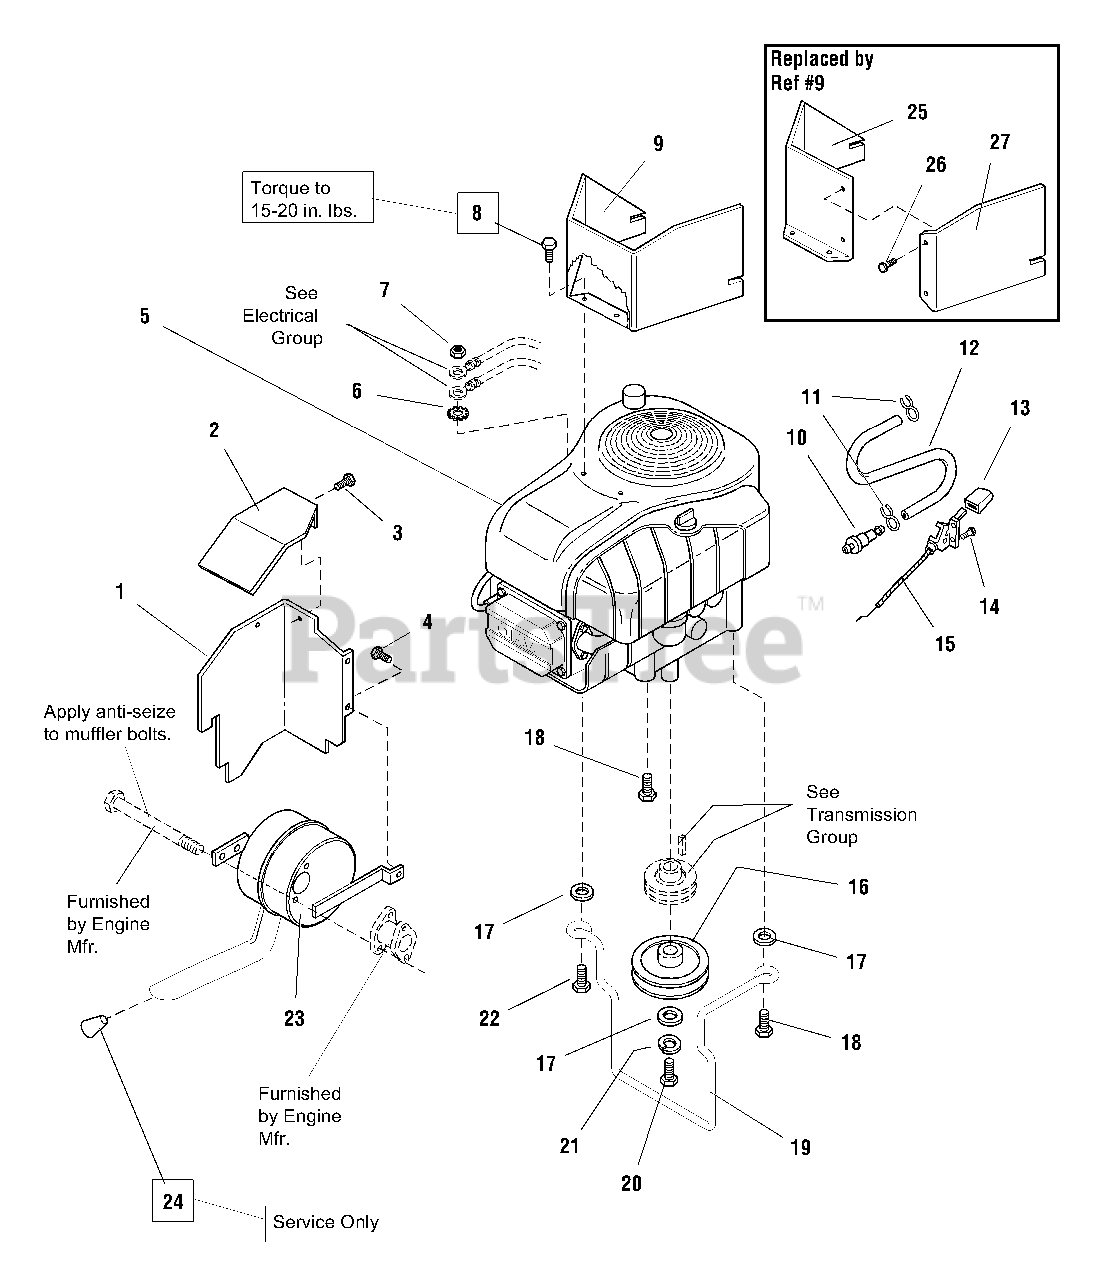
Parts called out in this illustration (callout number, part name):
1	SHIELD, Muffler Side
2	SHIELD, Muffler Top
3	CAPSCREW, Hex Washer Hd, Plastite, #10 - 14 x 5/8
4	CAPSCREW, Taptite Hex Washer Hd, 5/16-18 x 1/2
5	ENGINE, 14.5HP Briggs & Stratton INTEK
5	ENGINE, 15.5HP Briggs & Stratton INTEK
5	ENGINE, 17HP Briggs & Stratton INTEK
6	LOCKWASHER, External Tooth, 3/8
7	NUT, Hex, 3/8-16 NC-2B
8	CAPSCREW, Whiz Lock Hex Hd, 5/16-18 x 1/2
9	BAFFLE, Heat
10	FUEL FILTER
12	HOSE, Fuel, 1/4 ID x 1/2 OD x 12
13	KNOB, Throttle (Red)
14	CAPSCREW, Plastite Hex Washer Hd, 1/4-10 x 5/8
15	CONTROL, Throttle
16	PULLEY (with Hub)
17	WASHER, 7/16
18	CAPSCREW, Hex Washer Hd, Taptite, 3/8-16 x 1-1/2
19	GUIDE, Belt
20	CAPSCREW, Hex Hd, 7/16-20 x 2-1/2
21	LOCKWASHER, 7/16
22	CAPSCREW, Hex Washer Hd, Taptite, 3/8-16 x 2
23	MUFFLER ASSEMBLY
24	SCREEN, Exhaust
25	BAFFLE, Heat
26	CAPSCREW, Plastite Hex Washer Hd, #10-14 x 1/2
27	BAFFLE, Engine, LH
